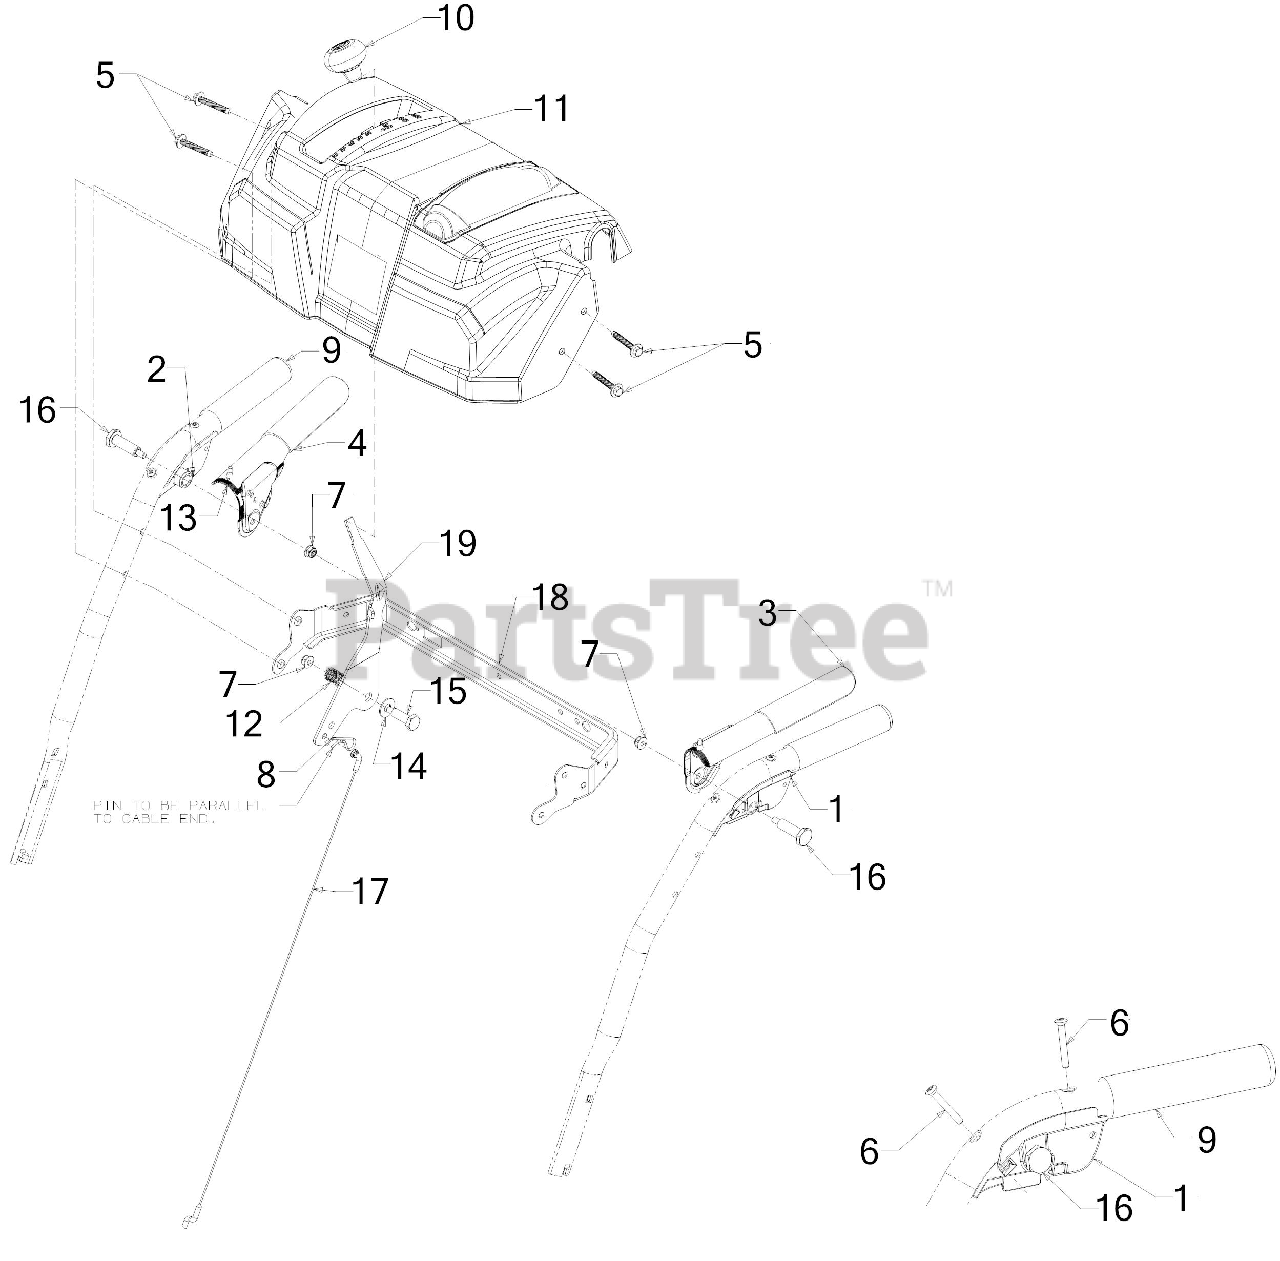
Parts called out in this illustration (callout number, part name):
1	CLUTCH LOCK HANLE ASSEMBLY (LH)
2	CLUTCH LOCK HANLE ASSEMBLY (RH)
3	HANDLE ASSEMBLY (LH)
4	HANDLE ASSEMBLY (RH)
5	SCREW 1/4-20 x 1.625
6	SCREW #10-24 x 1.375
7	FLANGE LOCK NUT
8	INTERNAL COTTER PIN
10	SHIFT KNOB
11	HANDLE PANEL
12	COMPRESSION SPRING
13	RUBBER BUMPER
14	FLAT WASHER
15	SHOULDER SCREW
16	SHOULDER SCREW .437 x 1.345 1/4-20
17	SPEED SELECTOR CABLE (PLASTIC)
